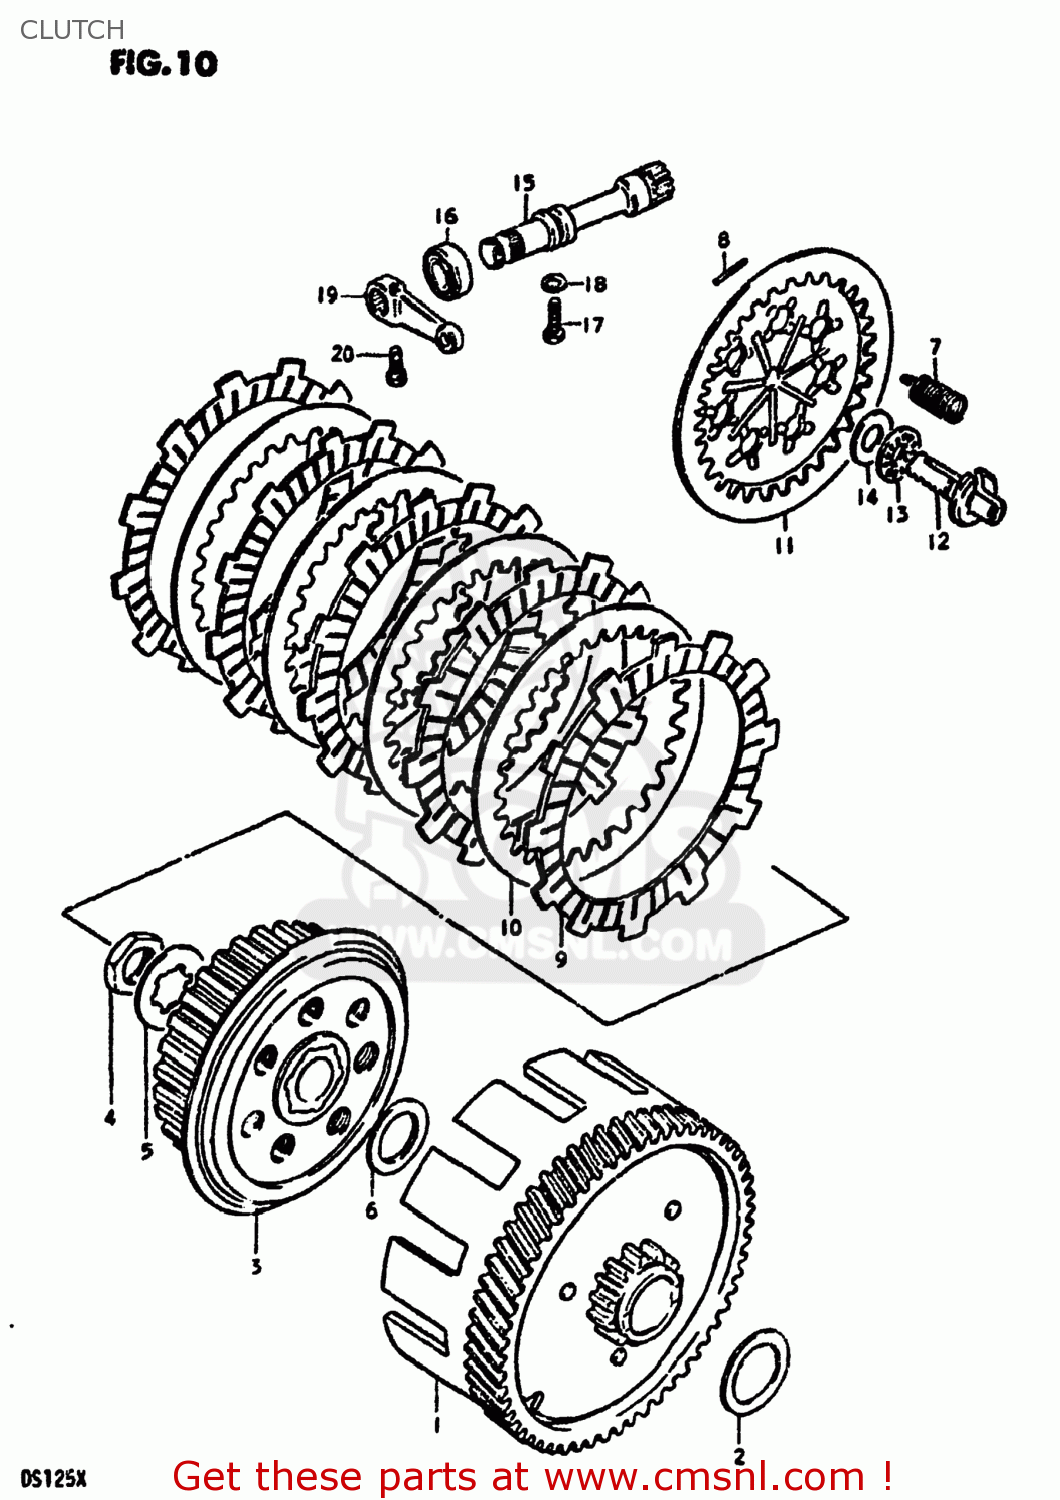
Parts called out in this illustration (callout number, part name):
1	GEAR ASSEMBLY,PRIMARY DRIVE
2	WASHER
3	HUB,CLUTCH SLEEVE
4	NUT
5	WASHER,LOCK
6	WASHER
7	SPRING
8	PIN(2.5X19.8)
9	PLATE,CLUTCH DRIVE
10	PLATE,CLUTCH DRIVEN (NAS)
11	PLATE,CLUTCH PRESSURE
12	BACK,CLUTCH RELEASE
13	BEARING(10X22X2.8)
14	WASHER(10.1X21.4X0.8)
15	PINION,CLUTCH RELEASE
16	OIL SEAL
17	BOLT(6X12)
18	WASHER
19	ARM,CLUTCH RELEASE
20	BOLT
